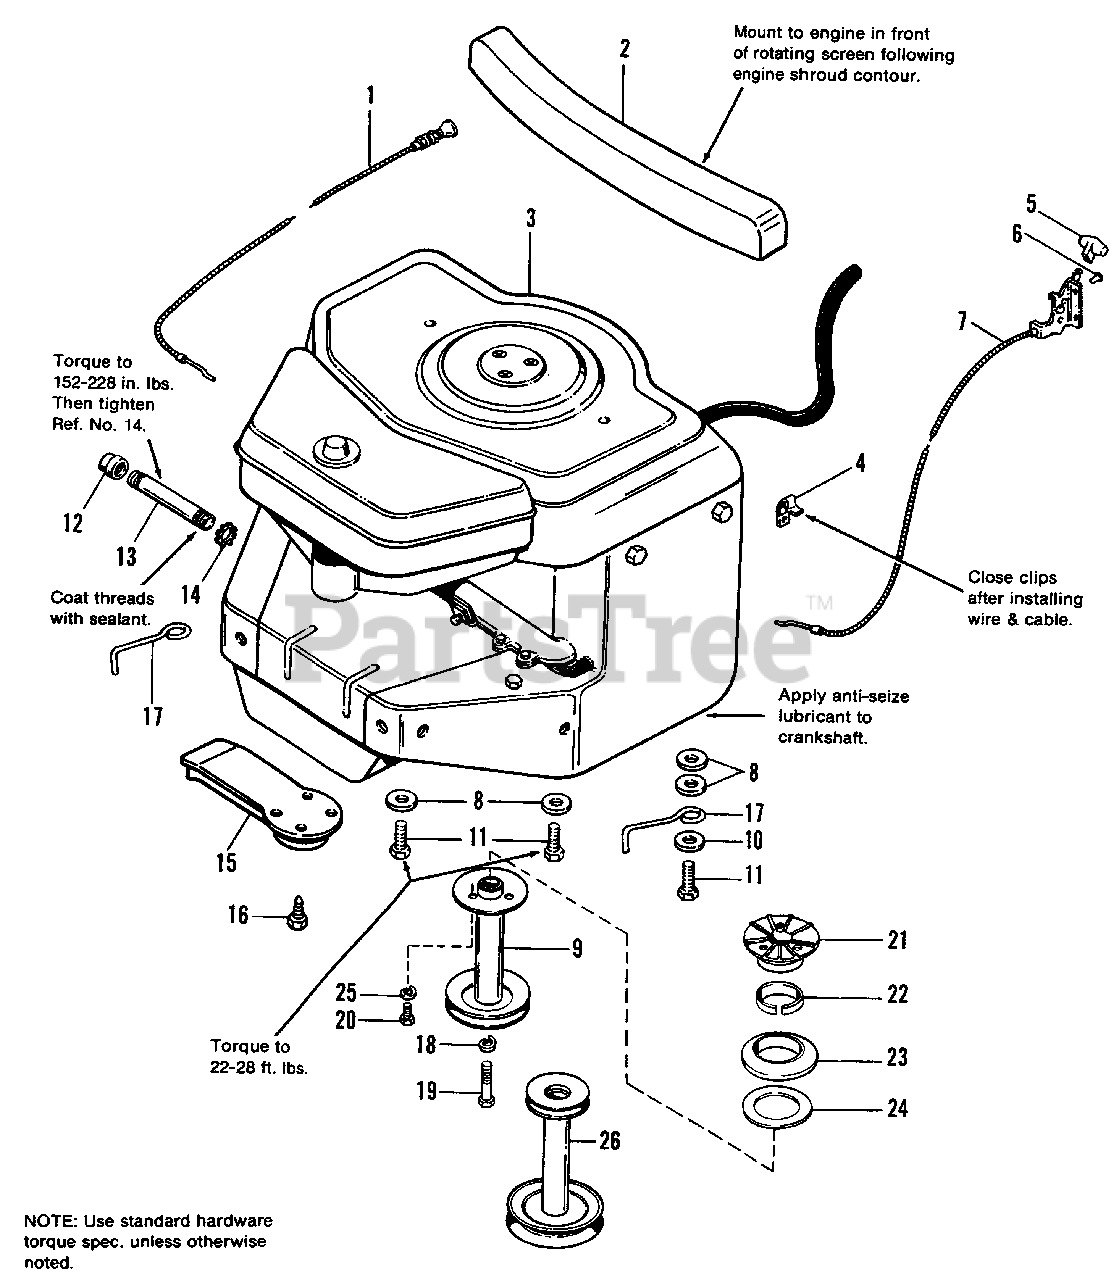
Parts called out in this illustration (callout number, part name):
2	BAFFLE, Engine, Rear
3	ENGINE ASSY., 16 HP Briggs & Stratton ENGINE ASSY., 18 HP Briggs & Stratton
4	CLAMP, Wire
5	KNOB, Throttle
7	CONTROL ASSY.
9	PULLEY ASSY., Engine
10	WASHER, Plain, 3/8
11	SCREW, Taptite, 3/8-16 x 1-1/2
12	PIPE, Cap, Hex
13	PIPE, Oil Drain
14	LOCKNUT, Conduit, 3/8
15	EXTENSION ASSY., Muffler
16	SCREW, Hex, Thd. Cutting, #8-32 x 3/8
17	STOP, Belt, Engine
18	LOCKWASHER, 7/16
19	CAPSCREW, 7/16-20 x 1-1/4
20	CAPSCREW, 5/16-18 x 3/4
21	PULLEY, Half, Upper
22	BEARING
23	PULLEY, Half, Lower
24	BEARING
25	LOCKWASHER, 5/16
26	PULLEY ASSY., Engine
